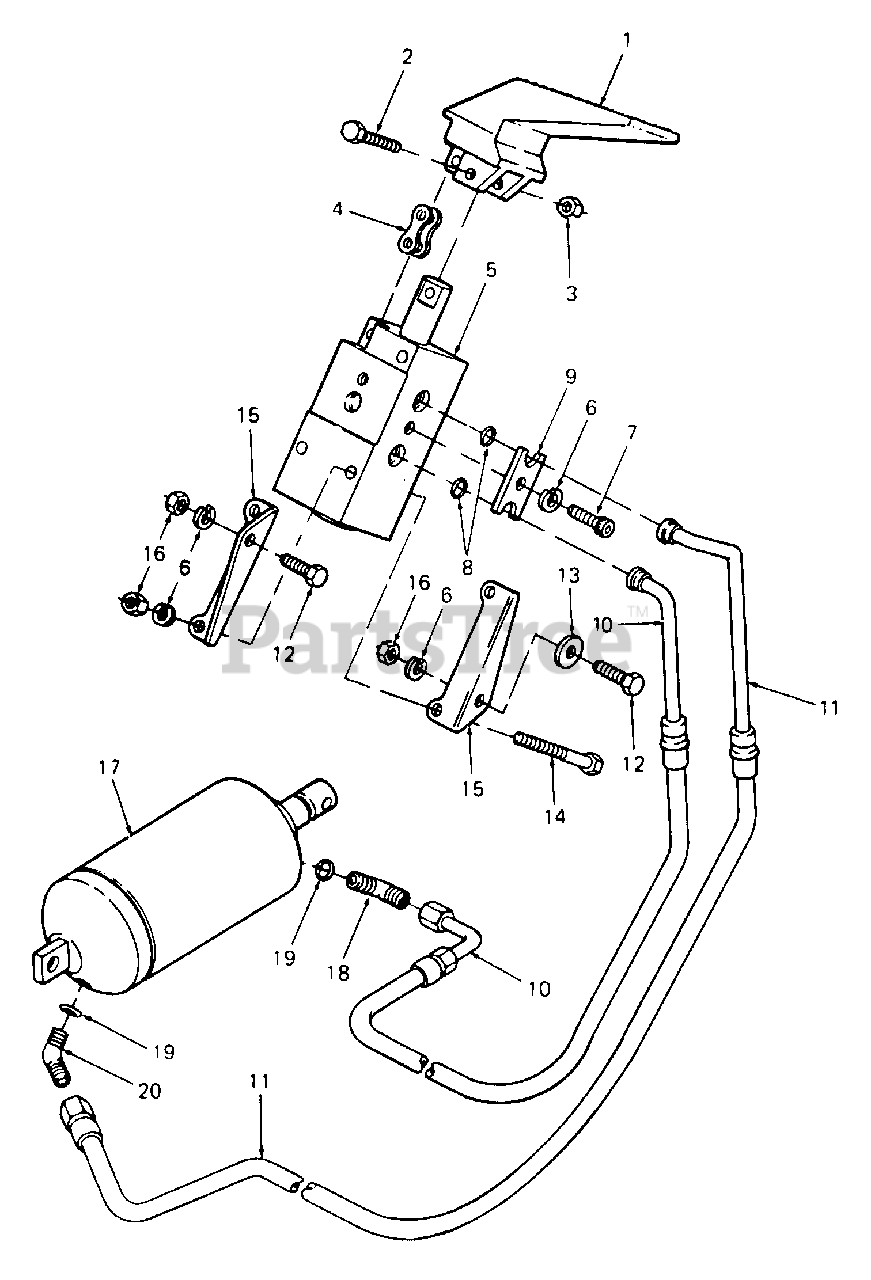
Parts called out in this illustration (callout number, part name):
1	Handle, Valve
2	Screw, Hex Cap, #10-24 x 1.0 Lg
3	Nut, Hex Center Lock, #10-24
4	Link, Chain
5	Valve, Lift
6	Washer, Lock, 1/4
7	Screw, Socket Hd Cap, 1/4-20 x .62 Lg GR8
8	O-Ring, .301 x .070 Dia
9	Clamp, Double
10	Hose, Cylinder-Contracting
11	Hose, Cylinder-Extending
12	Screw, Hex Cap, 1/4-20 x .62 Lg GR5
13	Washer, Bell, .265 x .75 x .062 Thk
14	Screw, Hex Cap, 1/4-20 x 2.25 Lg
15	Bracket, Valve Mtg
16	Nut, Hex, 1/4-20 GR5
17	Cylinder, Hydraulic
18	Elbow, 90 Deg w/O-Ring
19	O-Ring, 1/4 OD Tube
20	Elbow, 45 Deg w/O-Ring
